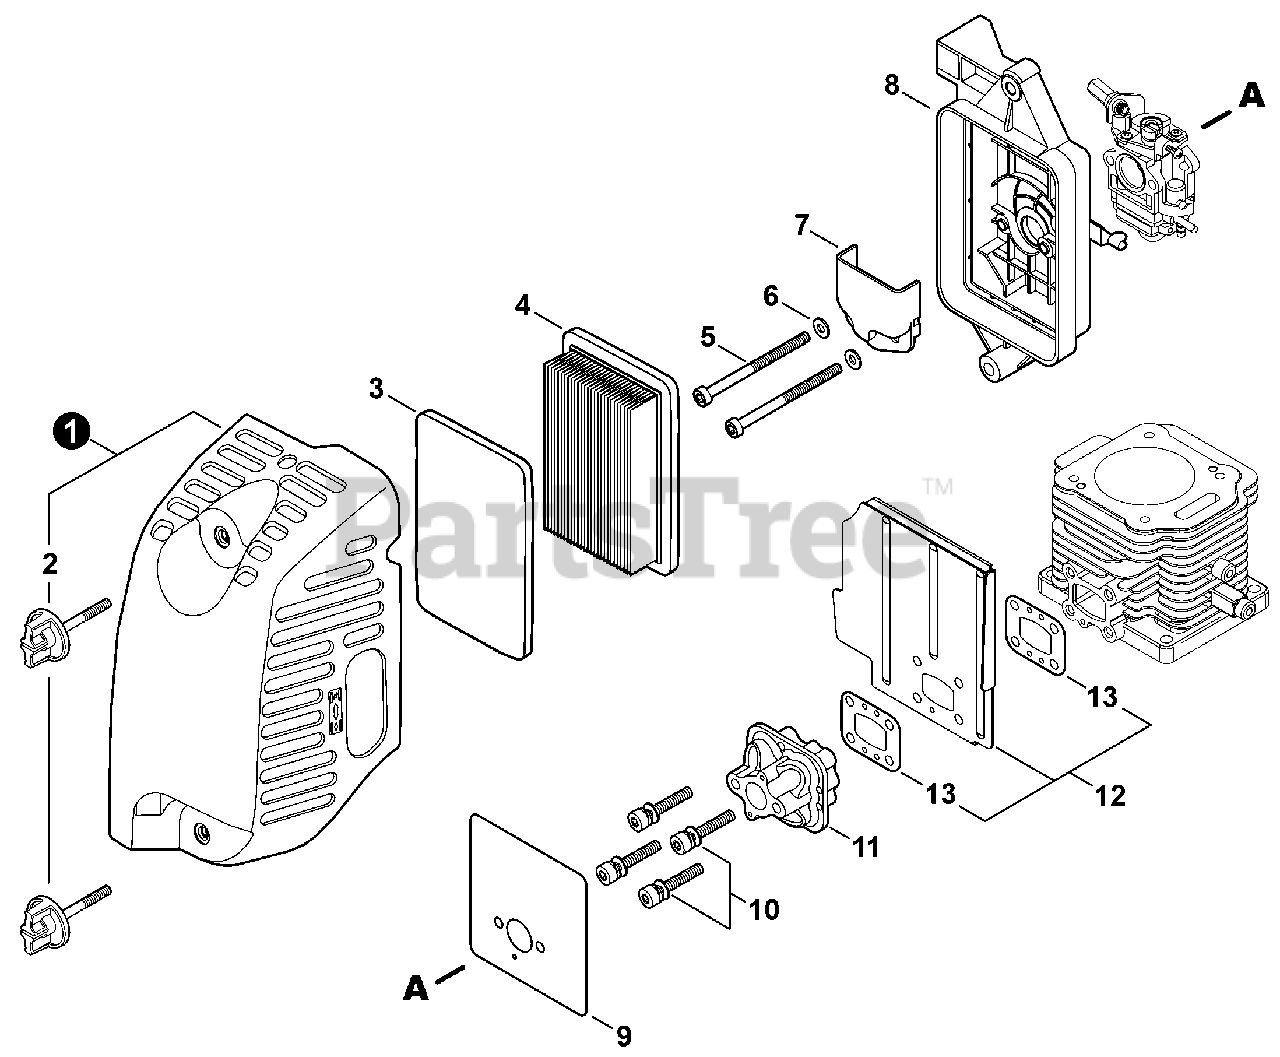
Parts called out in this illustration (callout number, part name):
1	COVER ASSY, AIR FILTER
2	THUMBSCREW
3	PRE-FILTER, FOAM
4	FILTER, AIR
5	BOLT SS M5×70
6	WASHER 5.5×12×0.8
7	PLATE, DEFLECTOR
8	CASE, AIR FILTER
9	GASKET, CARBURETOR
10	BOLT SS M5×30
11	INSULATOR, INTAKE
12	SHIELD ASSY, INTAKE HEAT
13	GASKET, INTAKE
